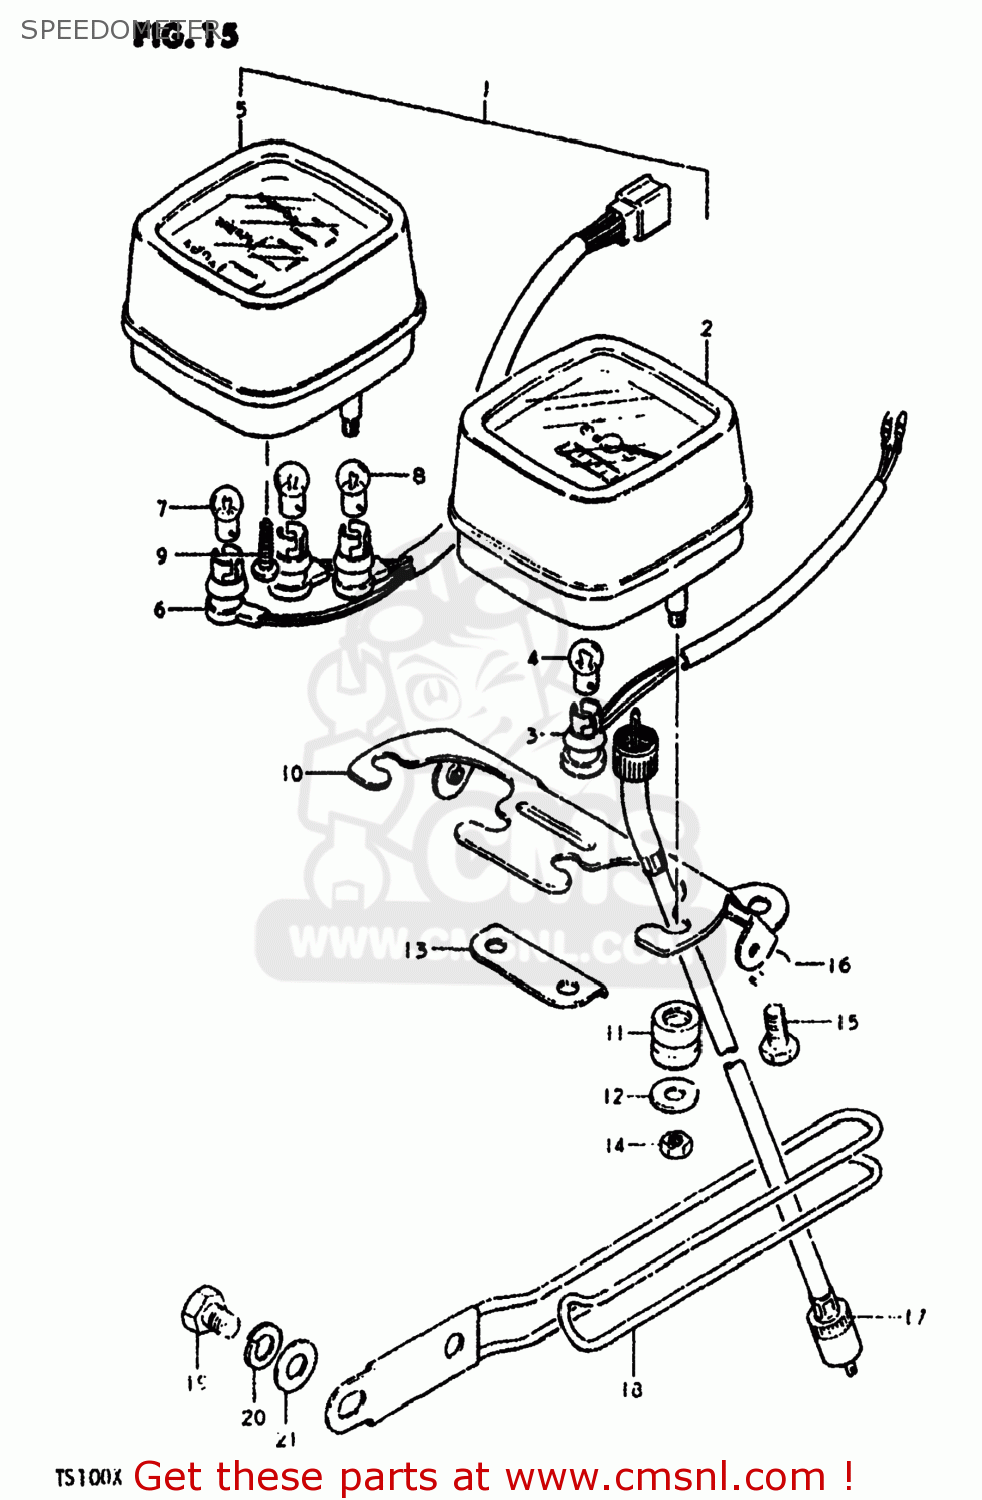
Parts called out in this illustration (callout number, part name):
1	SPEEDOMETER ASSEMBLY
2	SPEEDOMETER ASSEMBLY
3	SOCKET,SPEEDOMETER
4	BULB(6V/3W)
5	CASE,PILOT BULB
6	SOCKET
7	BULB(6V/3W)
8	BULB(6V1.7W,STANLEY,A61A)
9	SCREW
10	BRACKET,SPEEDOMETER
11	CUSHION
12	WASHER,METER
13	PLATE,METER CONNECTING
14	NUT
15	BOLT, UPPER
16	WASHER
17	CABLE ASSY,SPEEDOMETER
18	GUIDE,CABLE
19	BOLT 8X12
20	LOCK WASHER
21	WASHER
